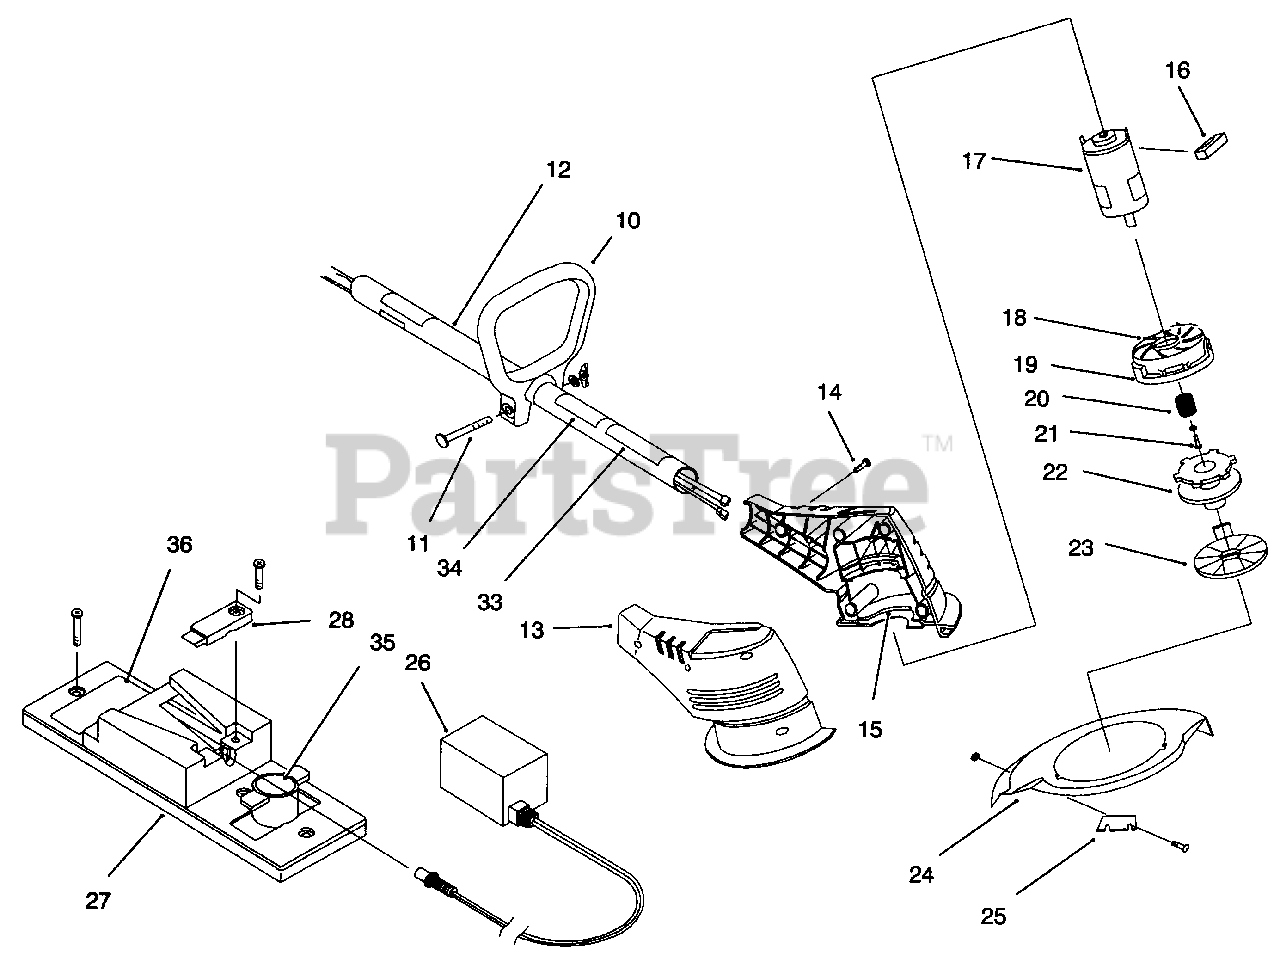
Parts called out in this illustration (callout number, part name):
10	D-Handle
11	D-Handle Hardware
12	Boom Assembly
13	Motor Housing
14	Housing Screw
15	Motor Supports
16	Anti-Rotation Block
18	Outer Spool and Eyelet (Incl. Ref. #19)
21	Screw & Washer
22	Inner Reel and .065 Line (15 ft.)
23	Reel Cove
24	Guard and Blade Assembly (Inc. Ref. #25)
25	Blade Assembly
26	Battery Charger
27	Wall Station Assembly
28	Wall Station Clamp & Screw
33	Decal-Safety Symbols
34	Decal-UL Safety Warnings
35	Decal-Toro Logo
36	Decal-Caution
